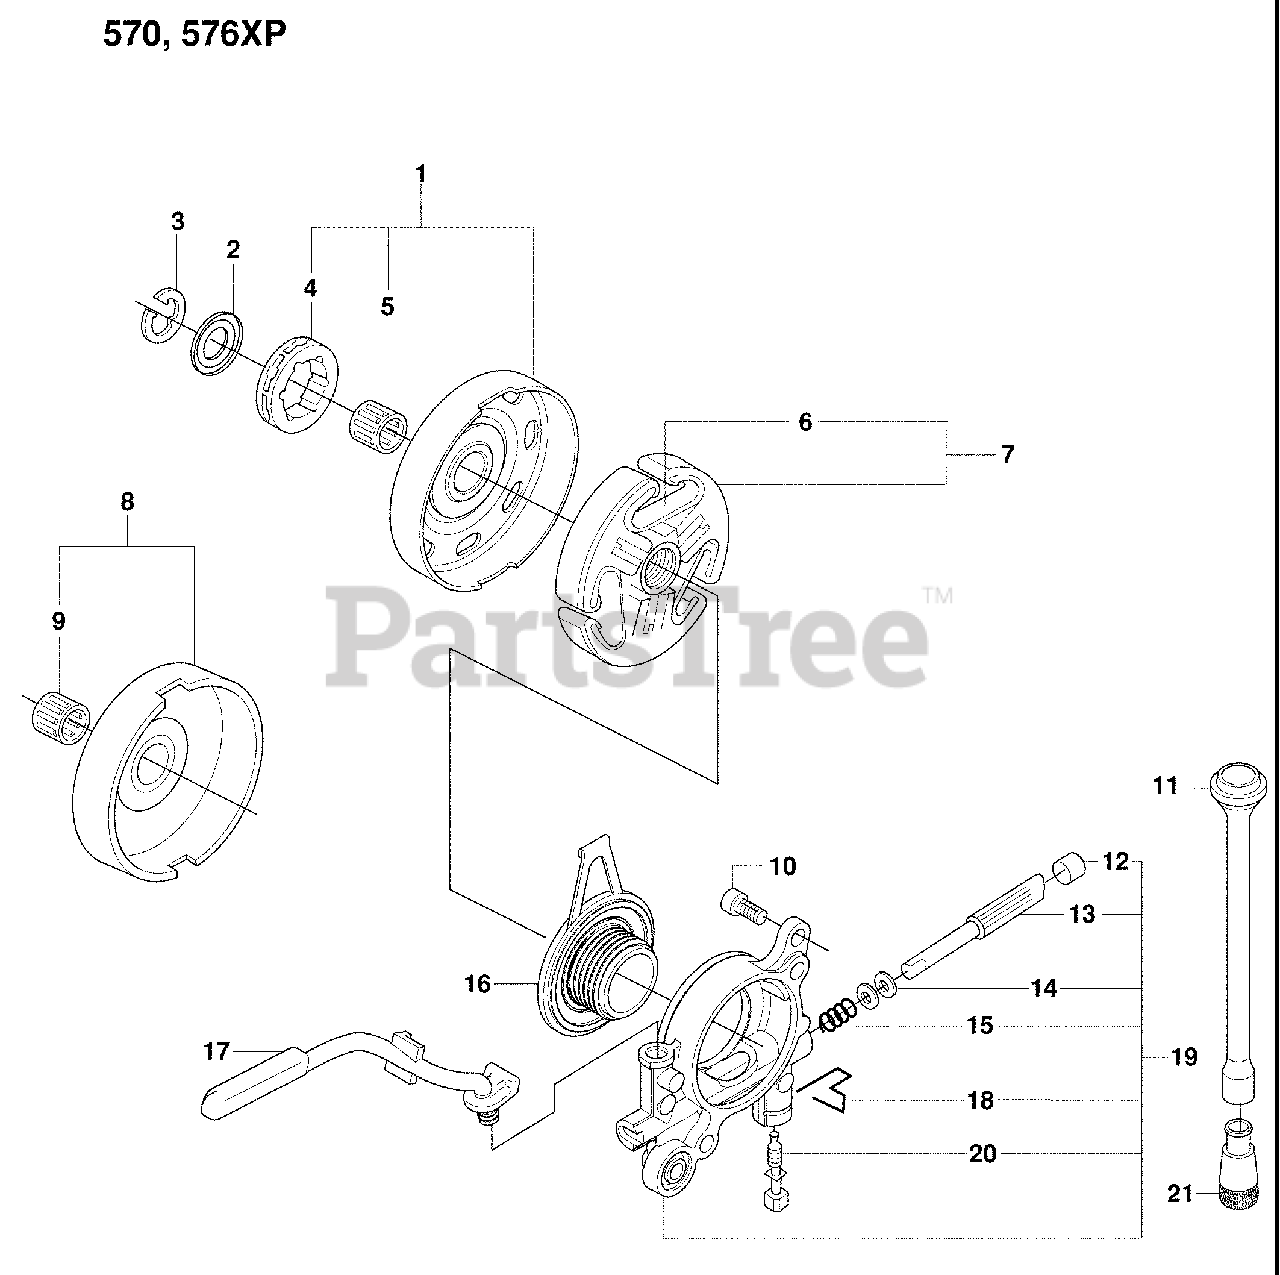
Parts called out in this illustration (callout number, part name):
1	Clutch Drum Assembly
3	Retaining Ring
4	Rim
4	Power Mate Rim
5	Clutch Drum Bearing
7	Clutch Assembly, M14 X 1.25-6H
8	Clutch Drum
9	Clutch Drum Bearing
13	Pump Piston
14	Washer, 6.1 X 9
16	Pinion
18	Spring Clip
19	Oil Pump
21	Oil Screen
